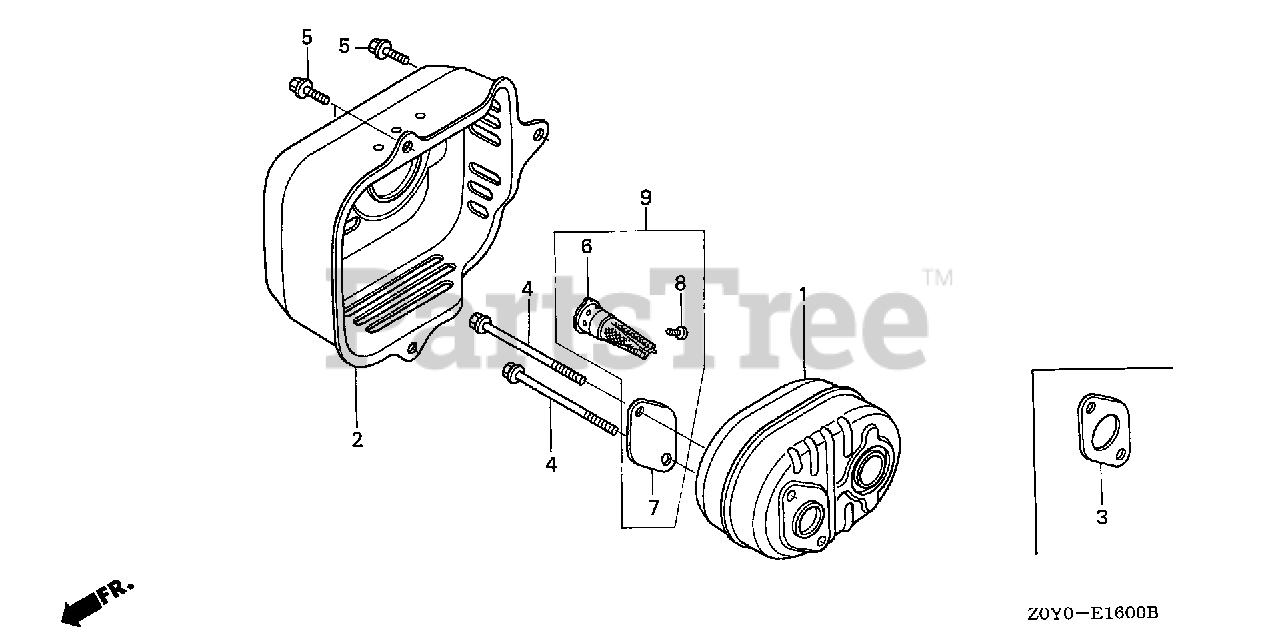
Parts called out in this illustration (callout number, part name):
1	MUFFLER
2	PROTECTOR, MUFFLER
3	GASKET, MUFFLER
4	BOLT, FLANGE (6X79) (CT200)
5	BOLT, FLANGE (6X12) (CT200)
6	ARRESTER, SPARK
7	PLATE, ARRESTER NUMBER
8	SCREW, TAPPING (4X6)
9	ARRESTER KIT, SPARK
